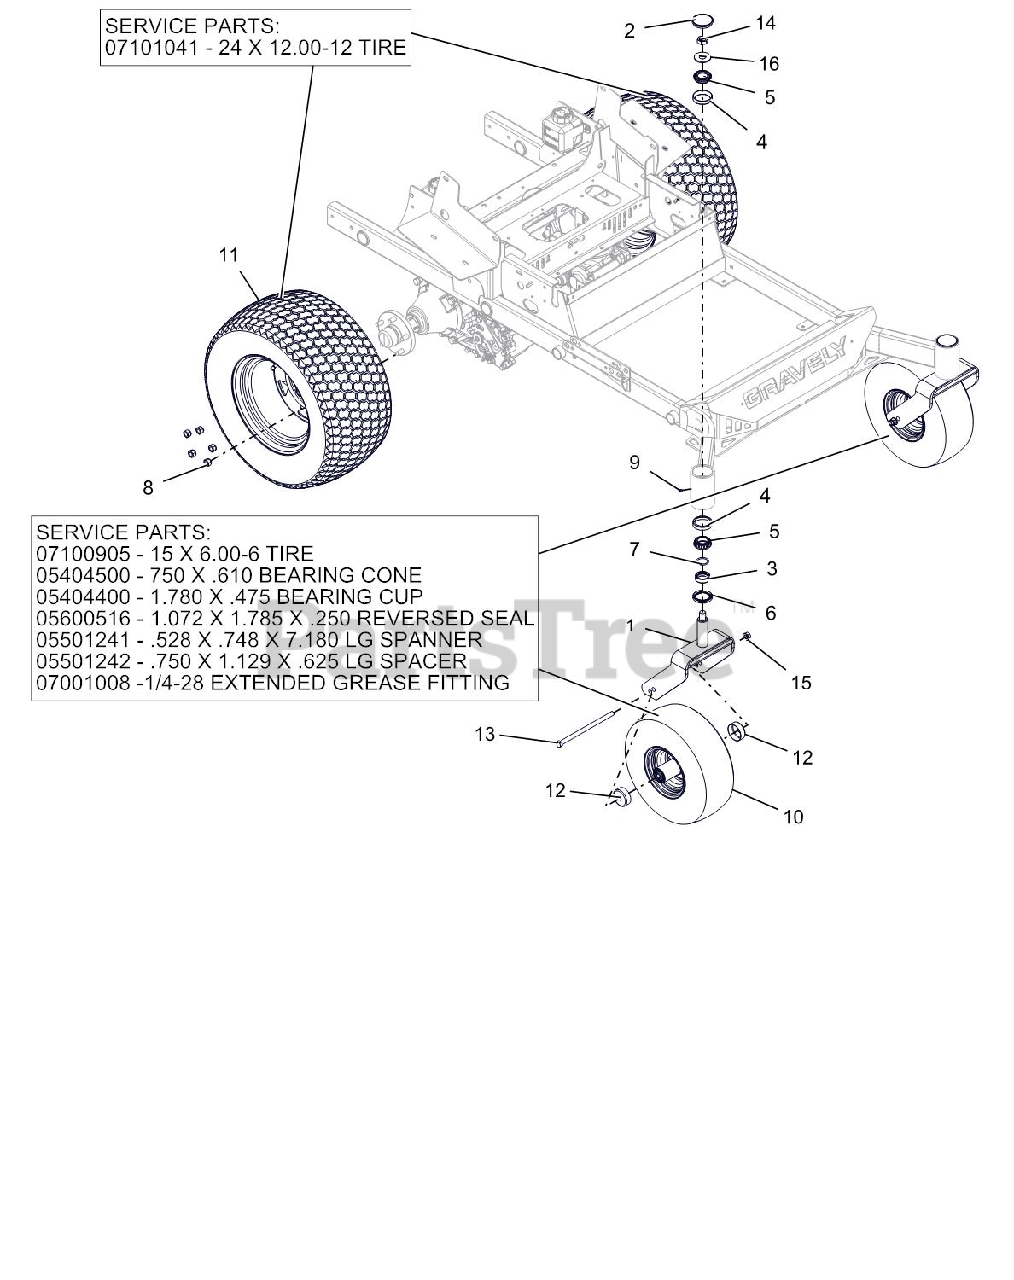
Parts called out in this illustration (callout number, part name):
1	CASTER FORK WMT - RED
2	CAP, DUST
3	SPCR, FRONT CASTER FORK
4	BRG-CUP 2.328X.465
5	BRG-CONE 1.25X.66
6	SEAL, OIL 1.75 X 2.332 X .312
8	WHEEL NUT .500-20 YZ
9	FTG, .25-28 FLUSH MNT GREASE
10	BRG-CONE .750X.61
10	BRG-CUP 1.781X.475
10	GREASE FITTING 1/4-28 EXTENDED
10	TIRE, 15X6-6 SMOOTH
10	SEAL,1.072X1.785X.250 REVERSED
10	ASM, WHL/TIRE 15X6.00-6 SMOOTH
10	SPANNER, .528X.748X7.18 LG
10	SPACER, .750X1.129X.625 LG
11	TIRE, 24 X 12.00-12
11	ASM, WHL/TIRE 24X12.00-12 K500
12	SHIELD, WHEEL BEARING
13	@BLT-HEX .50-13X9.00 GR5 YWZC
14	NUT-JAM TOPLK .75-16 YWZC
15	@NUT-LK-TOP-FLG .50-13 YWZC
16	@WSHR-FL-STL.812X2.00X.148YWZC
